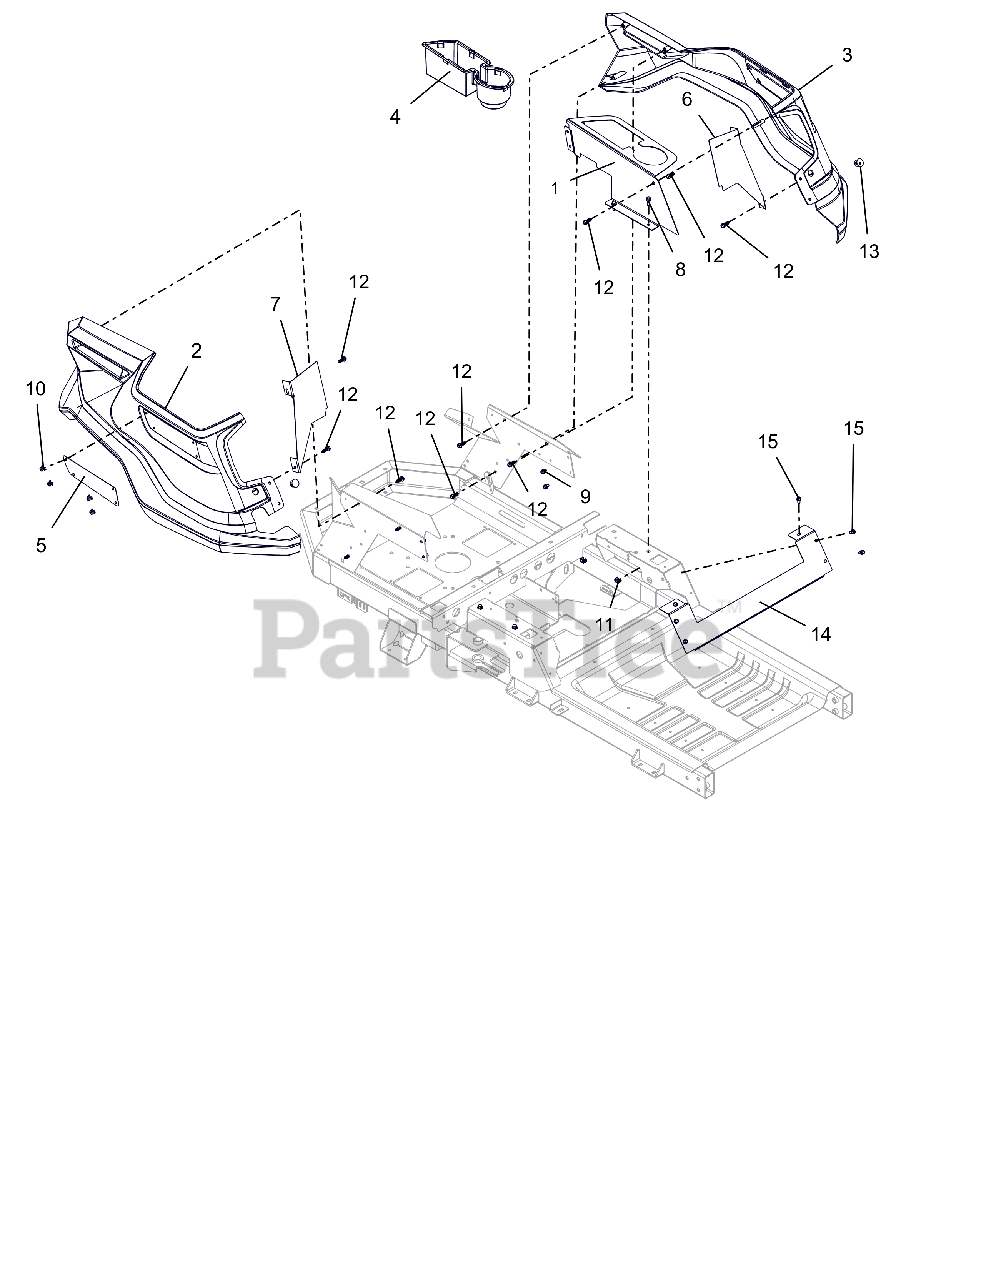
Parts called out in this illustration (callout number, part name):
1	PANEL, LEFT SIDE FENDER MOUNT
2	FENDER, RH IKON
3	FENDER, LH IKON
4	INSERT, CUP/STORAGE HOLDER
5	PLATE, ARIENS NAME
6	PLATE, LH BLOCKER
7	PLATE, RH BLOCKER
8	BLT,HEX-FLG .25-20X.75 G5 BFP
9	SCR,TAP .25-20X.375 HWH TR ZCC
10	RIVET, PLASTIC .195 DIA.
11	NUT RETNR .25-20
12	SCR-.312X.75 #14H H/W/H H/L CZ
13	PLUG, HOLE .75 (BLACK)
14	PLATE, SEAT KICK
15	SCR-TAP .25-20X.50 HWH ZCC
